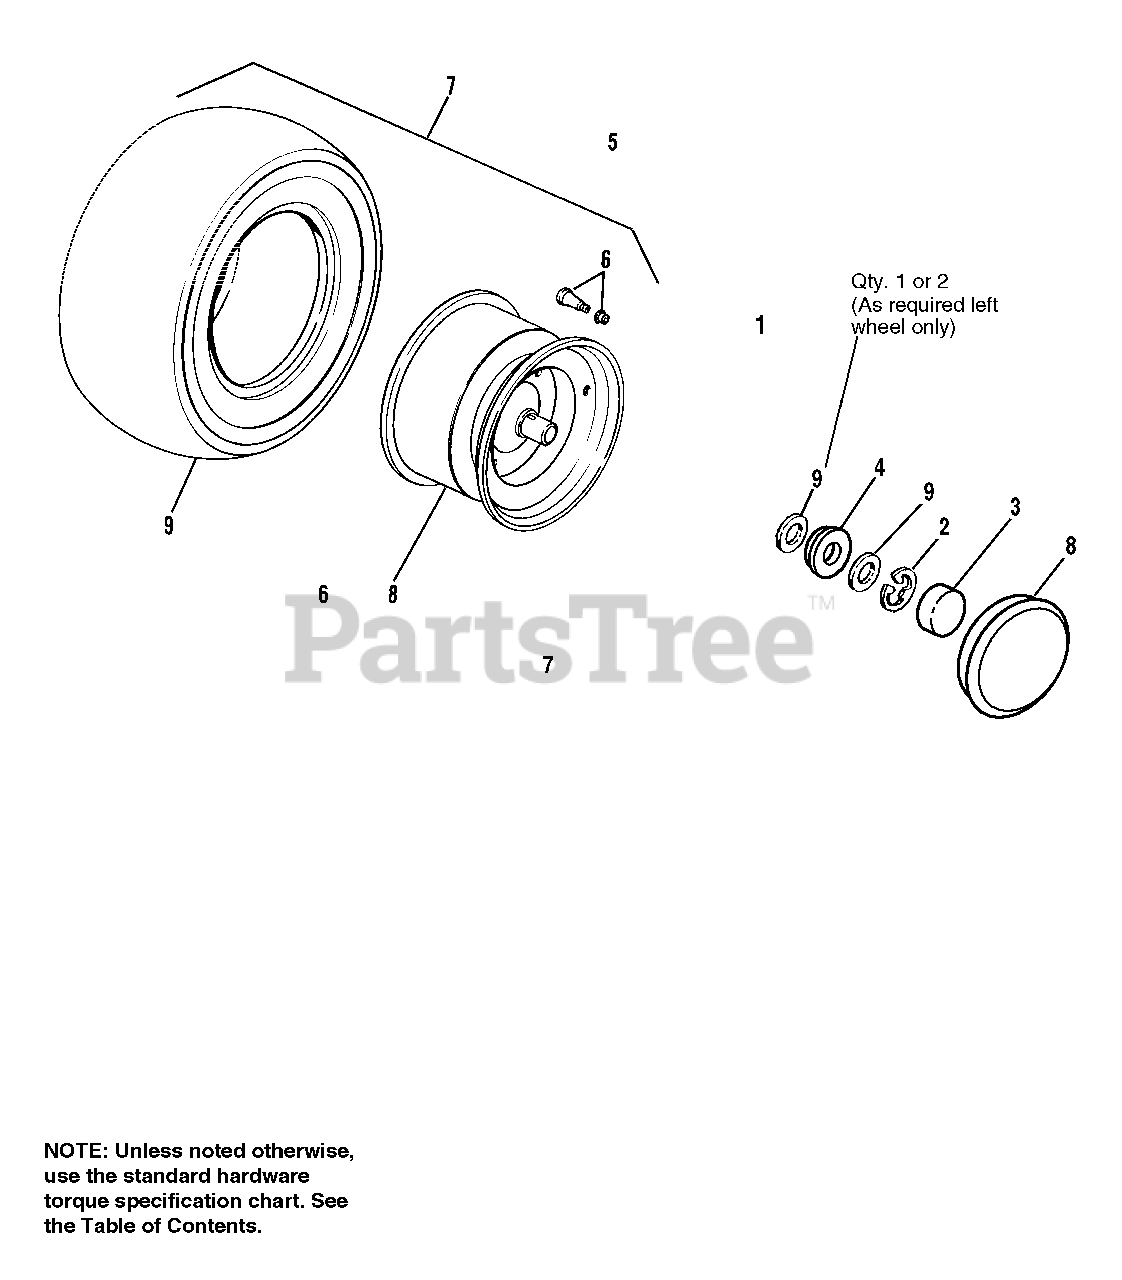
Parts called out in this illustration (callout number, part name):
1	VALVE STEM & CAP
3	HUB CAP
4	RETAINER, Hub Cap
5	REAR WHEEL & TIRE ASSY., Metallic Gray, 18 x 8.50-8
6	TIRE, Rear Wheel, 18 x 8.50-8
7	REAR WHEEL ASSY., Metallic Gray, 18 x 8.50-8
8	HUB CAP, 8"
9	WASHER, 3/4
